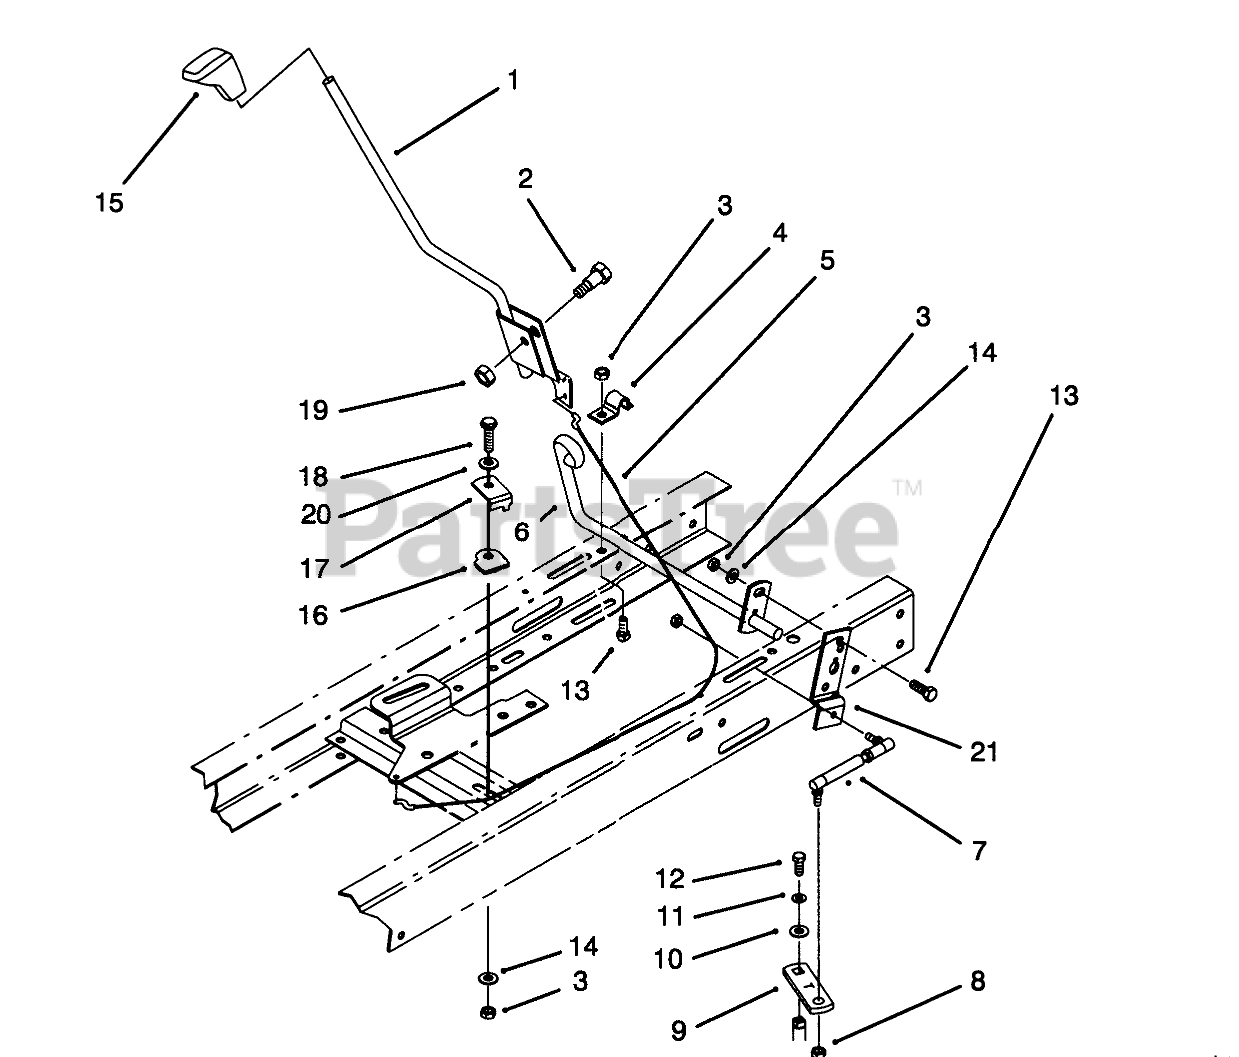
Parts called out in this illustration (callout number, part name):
1	Lever-Shift
2	SHOULDER BOLT
3	NUT-LOCK, NI
4	CLAMP-PIVOT, SHIFT
5	CABLE-CLUTCH
6	SHIFT PIVOT WAB
7	TIE ROD, SHIFT
8	NUT-LOCK
9	LEVER-SHIFT
10	SPACER
11	WASHER-LOCK
12	SCREW-HH
13	SCREW-HH
14	WASHER-PLAIN
15	SHIFT KNOB
16	GUIDE-CABLE
17	KEEPER-CABLE
18	SCREW-CARR
19	NUT-LOCK, NI
20	WASHER-FLAT
21	SHIFT LEVER PIVOTB
